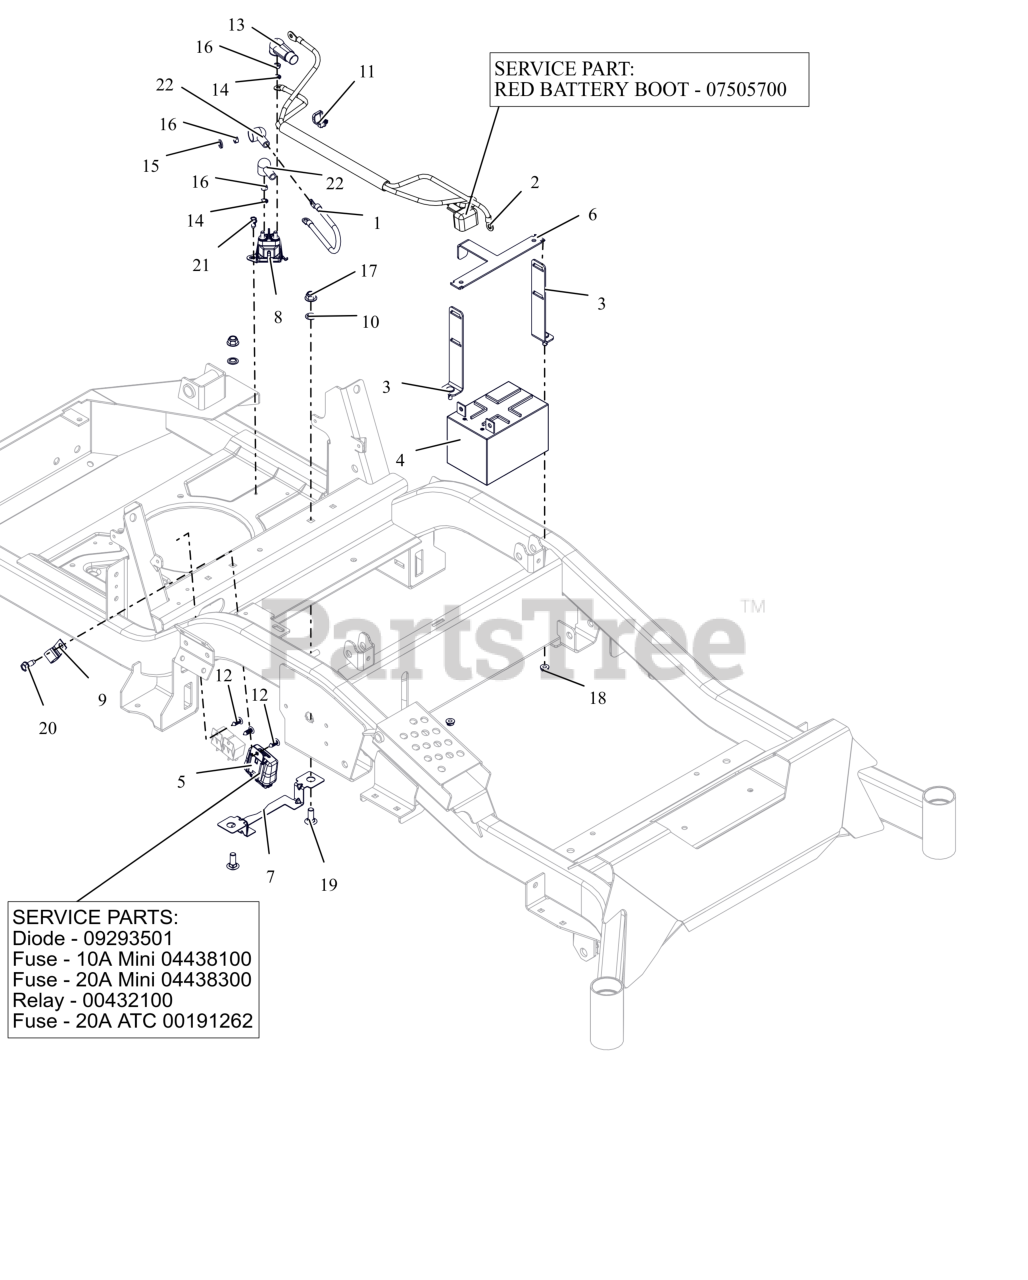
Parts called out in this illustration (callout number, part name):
1	CABLE, POS W/(2)1/4 RING 9.0LG
2	HARNESS, BATTERY HD
2	INSULATOR
3	WMT,BATTERY MOUNT HOLD DOWN
4	BATTERY, 12V 12A-190CCA
5	HARNESS, WIRE
5	DIODE, CONNECTOR SHELL
5	FUSE,10 AMP MINI-ATC
5	FUSE,20 AMP MINI ATC
5	RELAY,SEALED W/DIODE
5	FUSE, 20 AMP BLADE S/O
6	BRKT, BATTERY TIE DOWN
7	GUARD, ELECTRICAL HARNESS
8	SOLENOID, STARTER (SEALED)
9	J-CLAMP
10	NUT-PUSH .38 DIA. PAL ZINC
11	CABLE TIE W/ TREE (.25 HOLE)
12	RIVET, .25 NYLON PANEL
13	BOOT, .65ID POS
14	WSHR,LK-EXT.262X.502X.026 ZCC
15	WSHR,LK-REG .312X.078 ZCC
16	NUT-STD M6-1.0 ZCC
17	NUT,NYL-FLG .38-16 GF ZCC
18	NUT-LK-TOP-FLG .250-20 GF ZCC
19	BLT, RHSN .38-16X1.00 G5 ZCC
20	SCR,TAP .312-18X.75 HWH TR ZCC
21	SCR-TAP .25-20X.50 HWH ZCC
22	BOOT, EYELET TERMINAL
